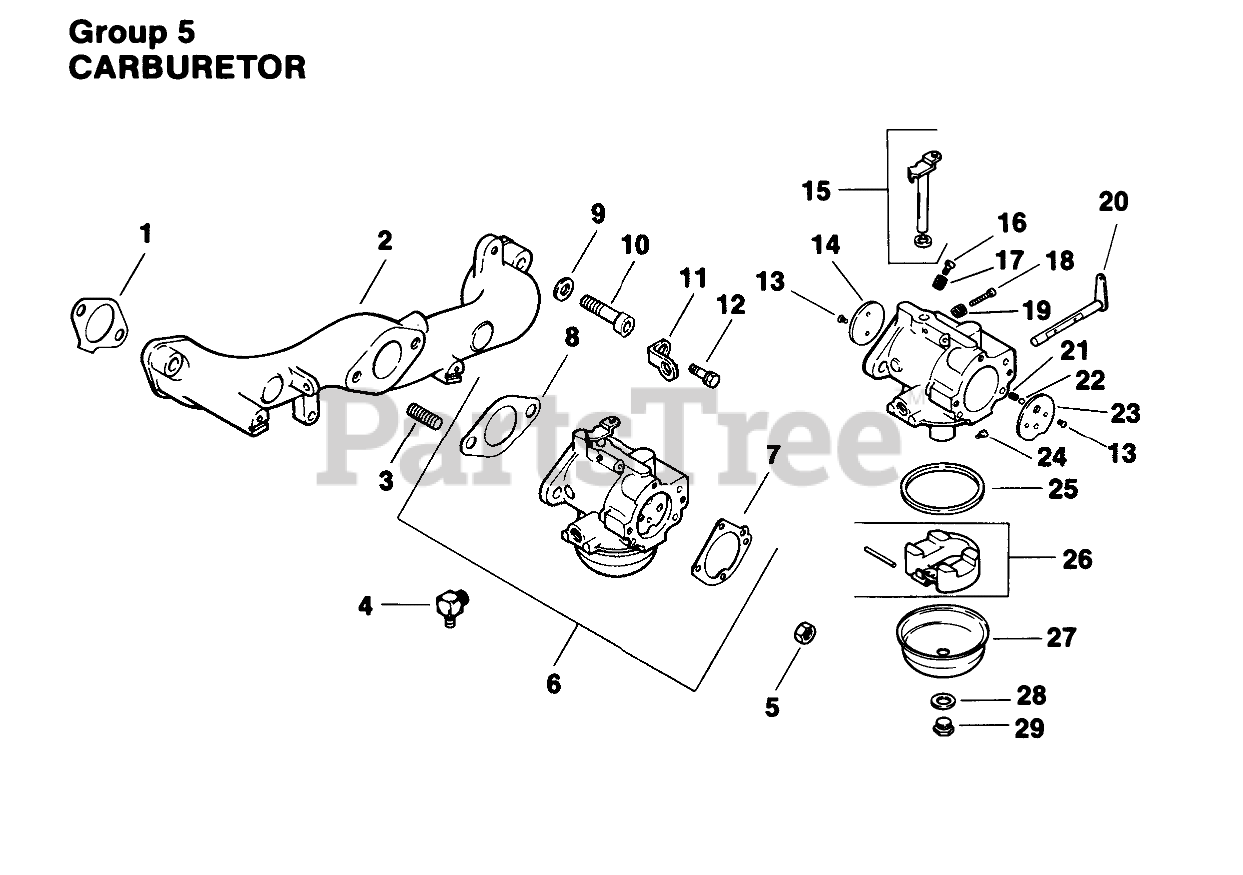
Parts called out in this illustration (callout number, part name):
1	Gasket-Intake Manifold
2	Manifold-Intake
3	Stud
4	Connector-90deg.
5	Nut
6	Carburetor Kit w/Linkage (Incl. Ref. #7-9, 14-30)
7	Gasket
8	Carburetor Assembly (For information only, not available separately).
9	Retainer-Spring
9	Gasket
10	Screw
11	Screw
12	Strap Lifting
13	Screw
15	Plate-Throttle
16	Shaft-Throttle w/Lever & Seal
17	Needle-Idle Fuel Adj
19	Screw-Idle Speed Adj
20	Spring-Adj
20	Seal-Rear Oil
21	Lever-Choke
24	Plate-Choke
25	Jet-Main
26	Gasket-Bowl
27	Kit-Float
28	Bowl-Fuel
28	Screw-Hex Washer Hd.
